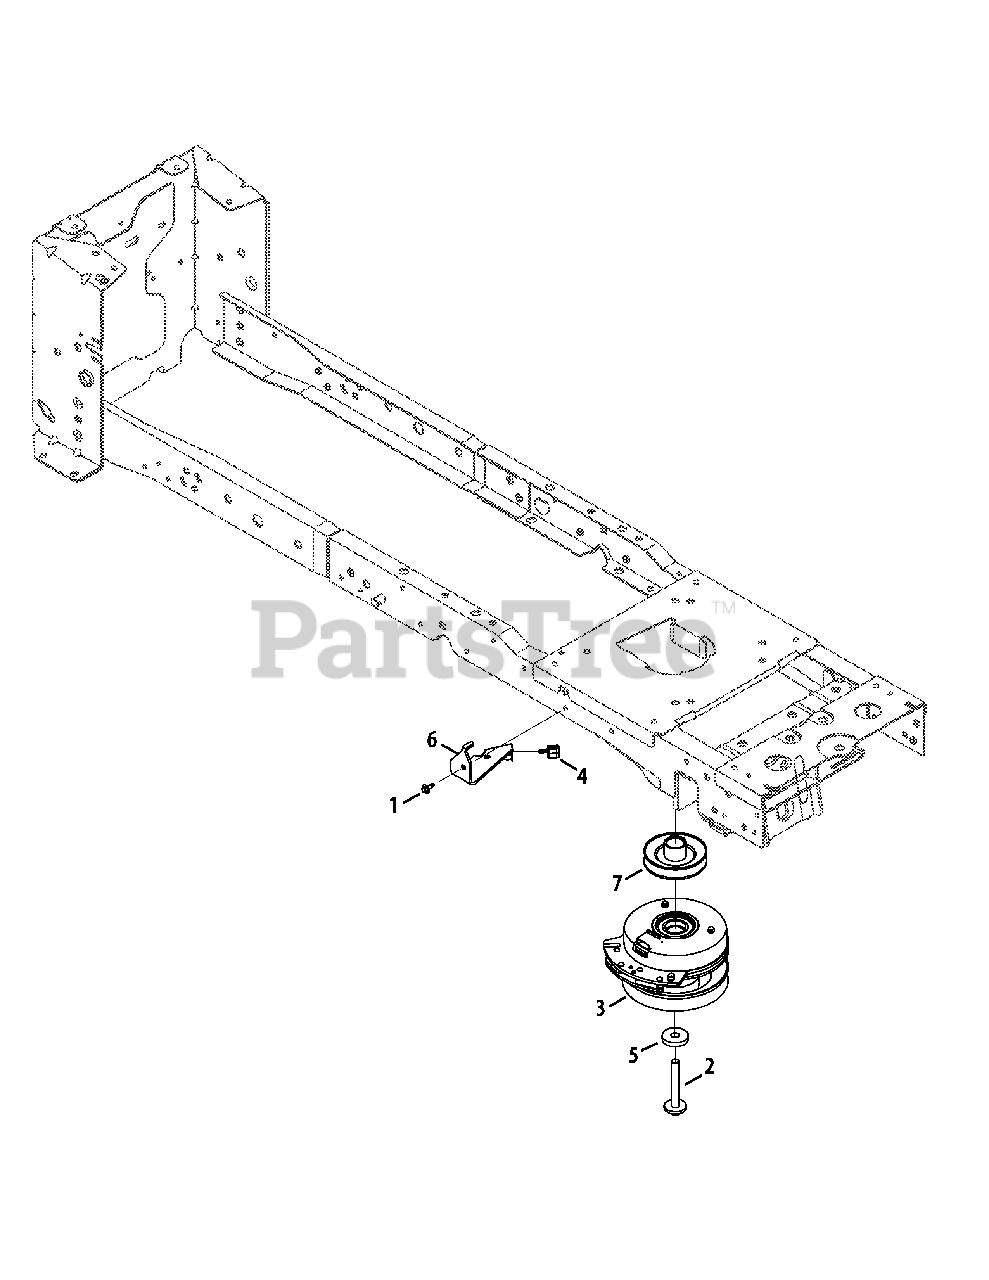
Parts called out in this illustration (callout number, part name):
1	Screw, M6-1 x .625
2	Hex Cap Screw, 7/16-20 x 3.50
3	Clutch, Electric PTO
4	Grommit
5	Flat Washer, .450 x 1.375 x .250
6	Clutch Bracket
7	Engine Pulley
